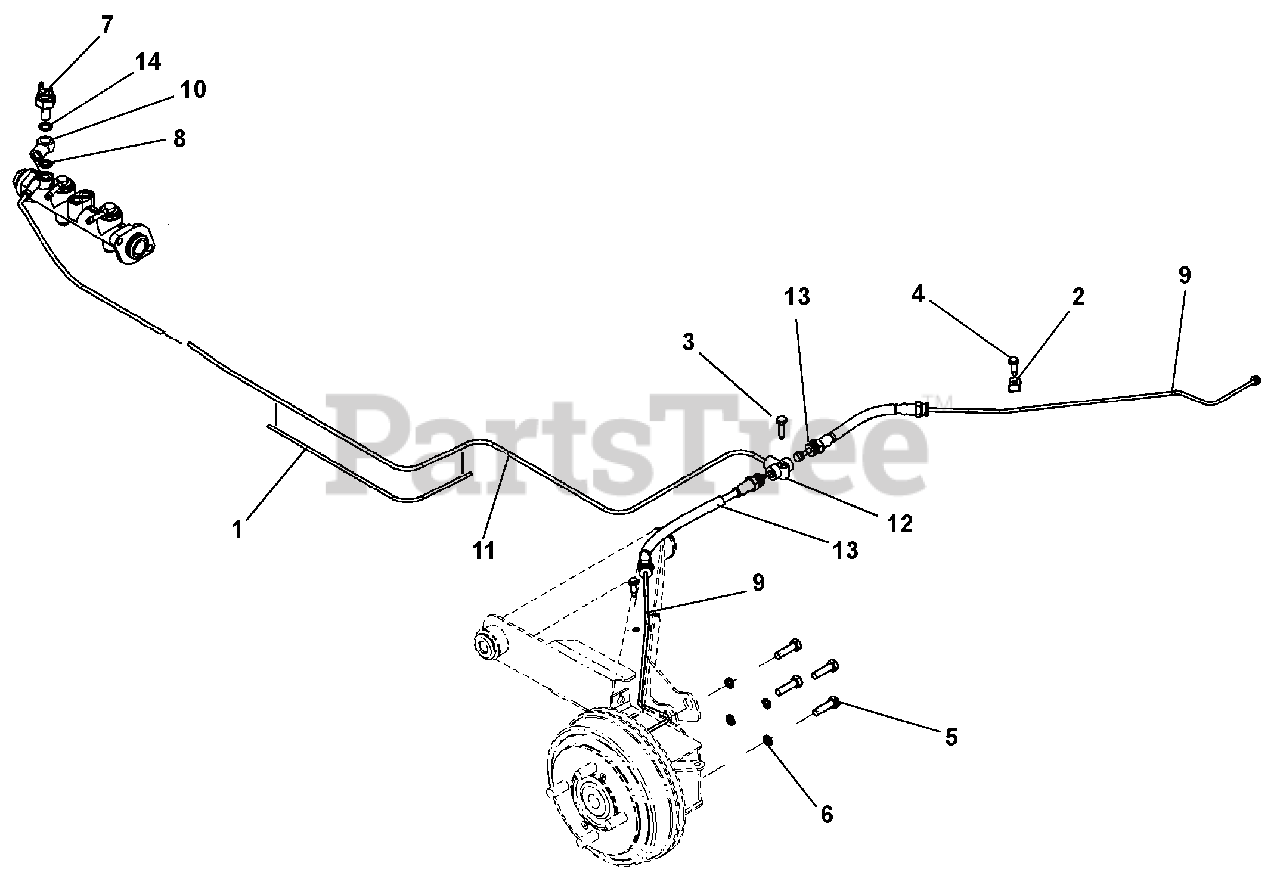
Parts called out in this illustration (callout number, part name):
1	CORRUGATED LOOM, .125 ID
2	WIRING/TUBE CLIP FOR 1/4 OD
3	SCREW HHC SELF TAP 1/4-20 X 1
4	HH DRILL SCREW 1/4 X 3/4 LG
5	HHCS M8X1.25 X 30 GR10.9 ZNYCR
6	WASHER LOCK M8 YWZC
7	BRAKE SWITCH, HIGH PRESSURE
8	WASHER, COPPER, 3.5 MM
9	REAR BRAKE LINE 28.3
10	BULK HEAD FLOW THROUGH
11	ST STEEL BRAKE LINE
12	FITTING 3 WAY HYD.
13	REAR RUBBER BRAKE LINE
14	MSTR CYL CPPR WSHR 16 X 10 X 1.5 MM
